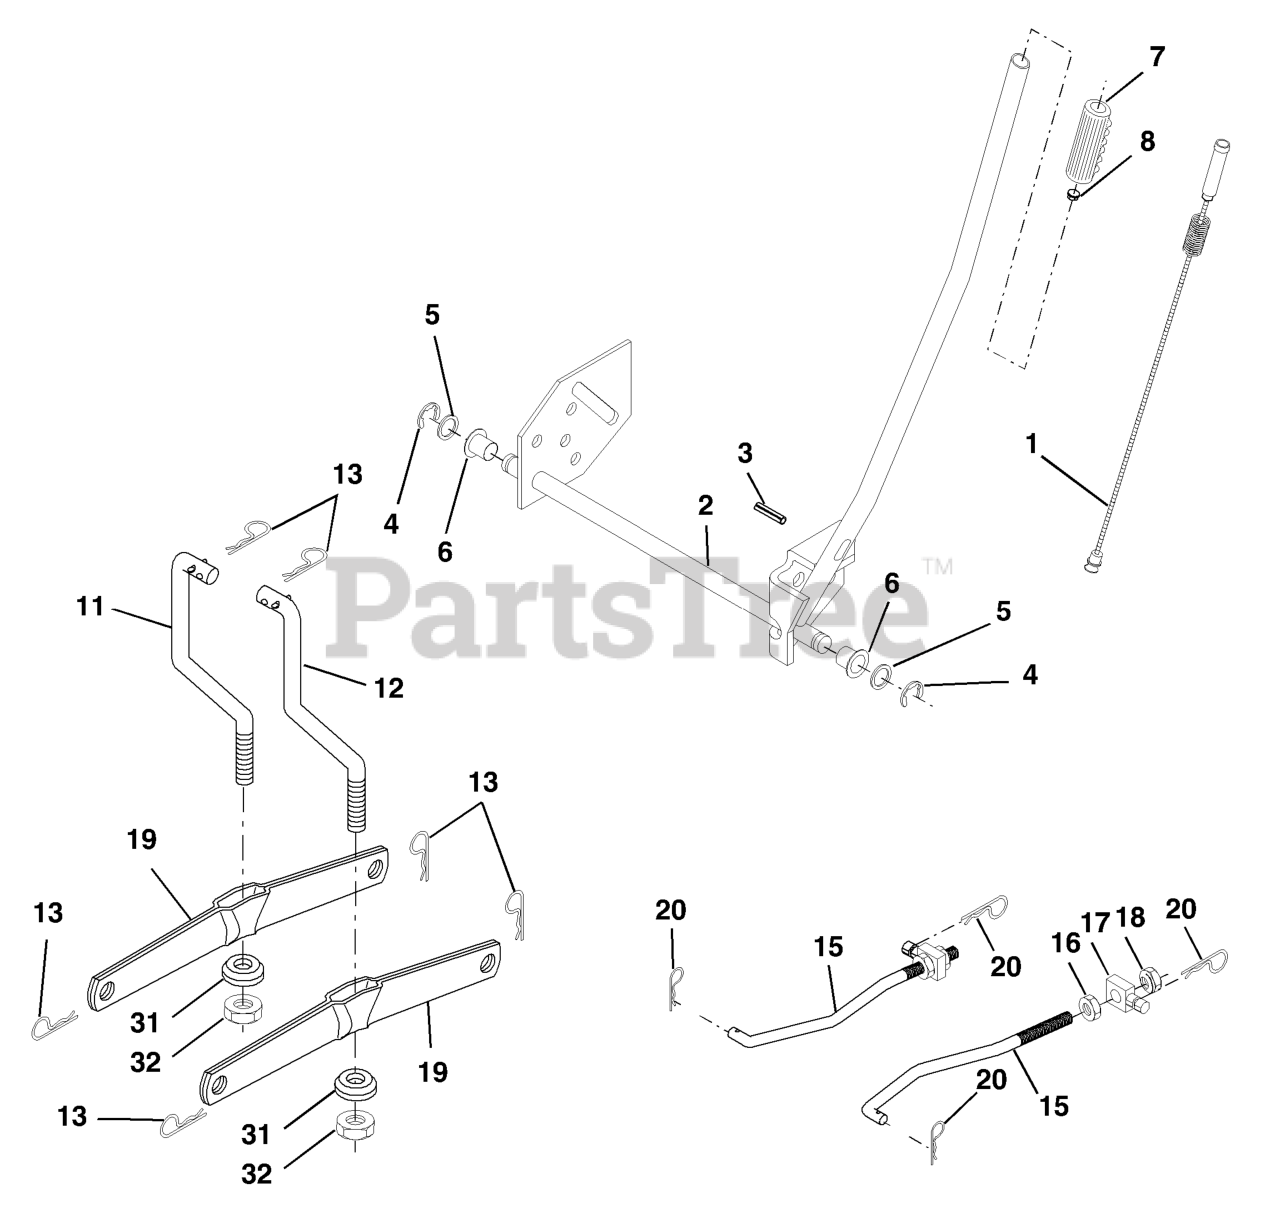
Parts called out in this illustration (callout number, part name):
1	WIRE ASM INNER W/ PLUNGER LT
2	SHAFT ASM R HANDLE
3	PIN GROOVE.
4	RETAINING RING LT
6	BEARING.NYLON
8	PLUNGER BUT KIT
11	LINK LIFT LH
12	LINK LIFT RH
13	RETAINER-SPRNG RB
15	LINK.SUSPENSION.FRONT
16	NUT.HEX.JAM.1/2-13
18	NUT.LK.W/WSH.1/2.
19	ARM.REAR.SUSPENSION
20	SPRING RETAINER
31	BEARING.PIVOT.LIFT
32	NUT CROWNLOCK 3/8-24
